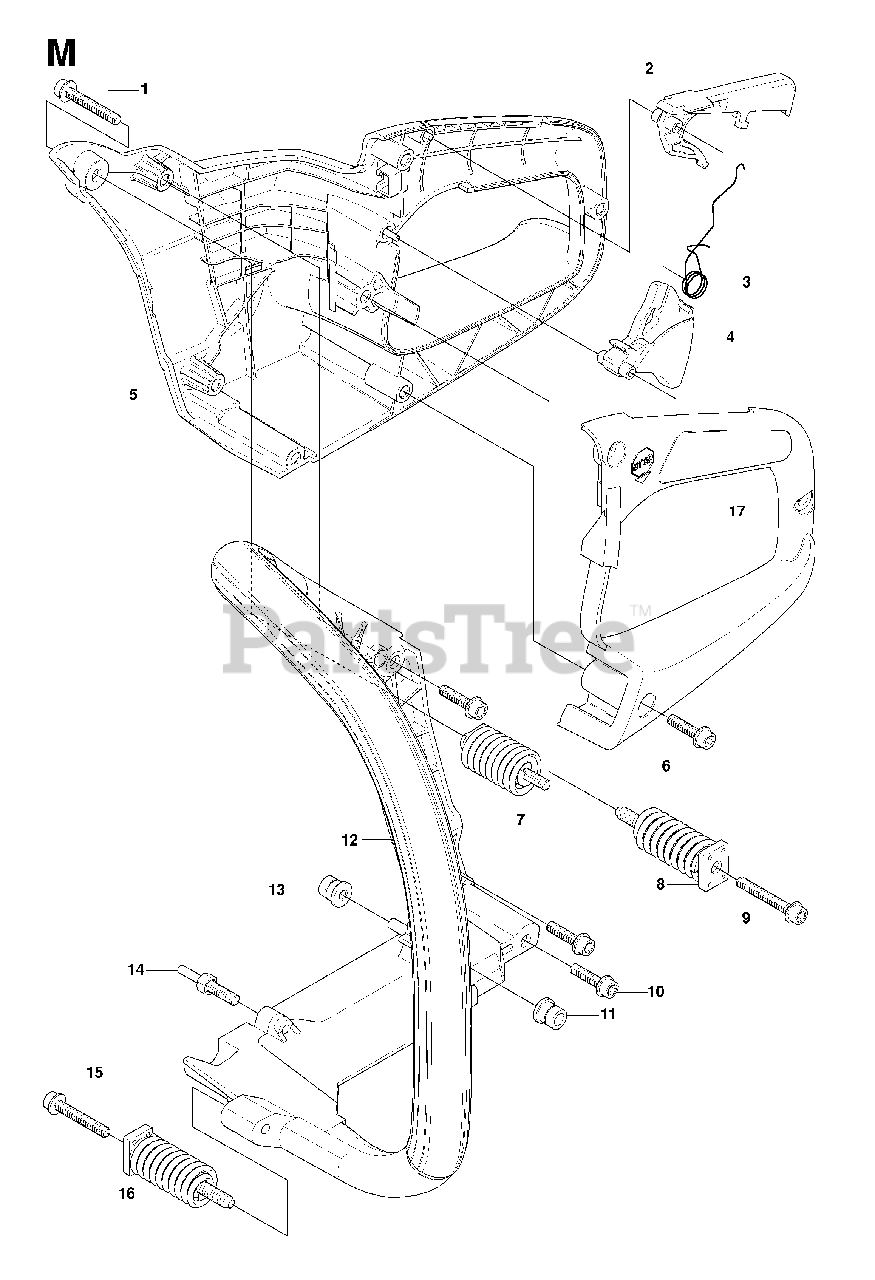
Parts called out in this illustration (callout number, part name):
1	%SCREW
2	THROTTLE LOCKOUT
4	THROTTLE TRIGGER
5	REAR HANDLE
7	VIBRATIONS ABSORBER
8	VIBRATION ABSORBER
11	MOVEMENT LIMITER
12	FRONT HANDLE
13	MOVEMENT LIMITER
